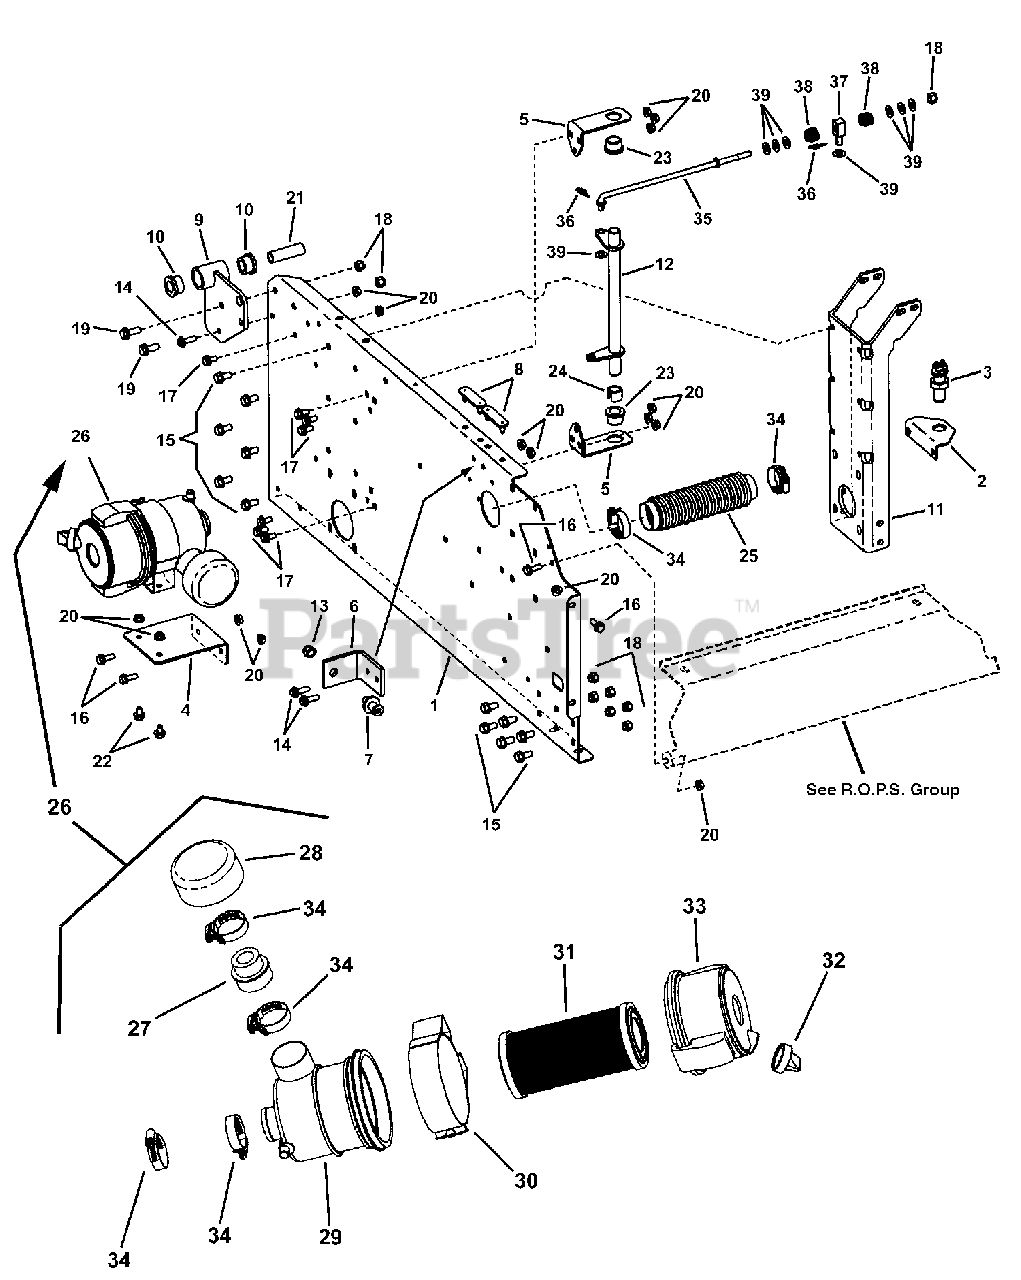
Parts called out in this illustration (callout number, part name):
1	FRAME, Rear, RH, Used on Turf Cruiser Models 85632 & 85668
1	FRAME, Rear, RH, Used on Trail Cruiser Model 85903
2	BRACKET, Speed Sensor (weldment)
3	SENSOR, Speed
4	BRACKET, Air Filter
5	BRACKET, Transmission Shift
6	BRACKET, Bed Latch
7	PIN, Bed Latch Striker
8	BUMPER, Rubber
9	PIVOT ASSEMBLY, Dump Bed, Used on Turf Cruiser Models 85632 & 85668
9	PIVOT ASSEMBLY, Dump Bed, Used on Trail Cruiser Model 85903
10	BUSHING, Suspension
11	STIFFENER, CVT Frame, Used on Turf Cruiser Models 85632 & 85668
11	STIFFENER, CVT Frame, Used on Trail Cruiser Model 85903
12	SHAFT ASSEMBLY, Shifter
13	NUT, Hex Nyloc, 7/16-14
14	BOLT, Hex Flange Lock, 5/16-18 x 1
15	SCREW, Hex Washer Self-Tap, 3/8-16 x 3/4
16	BOLT, Hex Flange Lock, 5/16-18 x 7/8
17	BOLT, Hex Flange Lock, 5/16-18 x 5/8 GR 5
18	NUT, Hex Nyloc, 3/8-16
19	BOLT, Hex Flange Lock, 3/8-16 x 1 GR 5
20	NUT, Hex Flange Lock, 5/16-18 GR 5
21	SLEEVE, Suspension
22	BOLT, Hex Flange Lock, 5/16-18 x 1/2
23	BEARING, .750 I.D.
24	RING, Blue
25	FLEX TUBE, 1.75 x 1.75 x 12
26	ASSEMBLY, Air Filter (Includes Ref. Nos. 27 thru 34)
27	RESTRICTER, Air Cleaner
28	PRECLEANER, Air Filter
29	HOUSING, Air Filter
30	BRACKET, Air Filter Mounting
31	ELEMENT, Air Filter
32	VALVE, Air Filter Drain
33	CAP, Air Filter
34	CLAMP, Hose
35	ROD, Transmission Shift (3/8-16 thread)
36	COTTER PIN, 3/8 Self Lock
37	SWIVEL, 3/8 w/thru hole
38	SPRING, Friction Pack
39	WASHER, 3/8 SAE Flat
